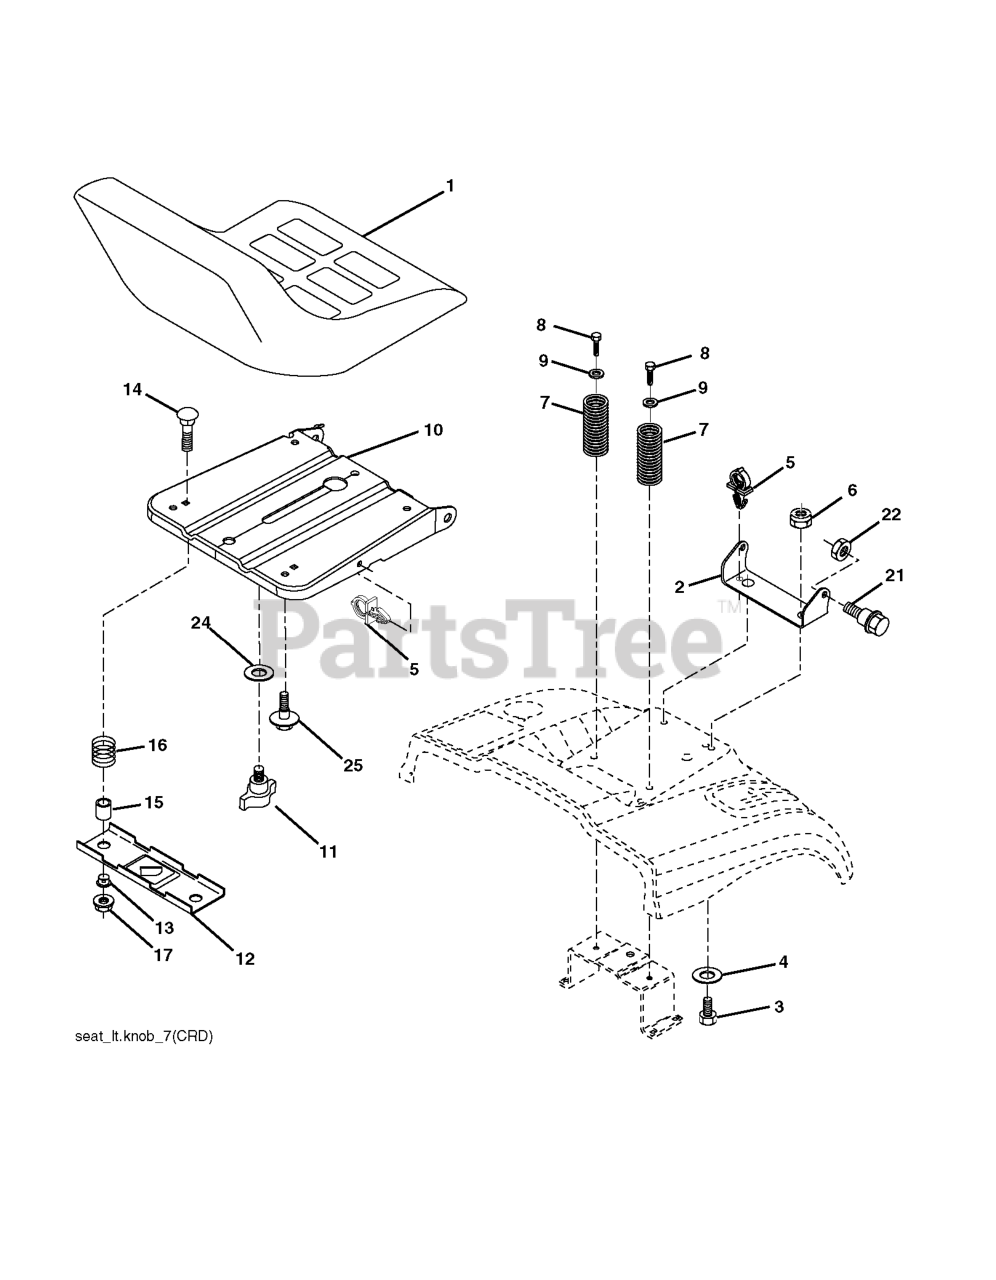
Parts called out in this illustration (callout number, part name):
1	RP SEAT
2	SEAT PIVOT BRKT
3	BOLT, HEX 3/8-16X1
6	NUT
7	SPRING COMPRESSION
8	SCREW 3/8-16X1
9	WASHER
10	PAN.ASM.SEAT.1SLOT
11	KNOB.SEAT.ADJ.WINGNUT
12	BRKT.MNTNG.SWITCH.SEAT.BLACK
14	BOLT.ROUND.HEAD.SQUARE.NECK
15	SPACER SPLIT 28X.96
17	NUT T
21	BOLT.SHOULDER.5/16-18
22	NUT.71038.31-18.HEX.NYLOCK
25	BOLT,SHOULD
